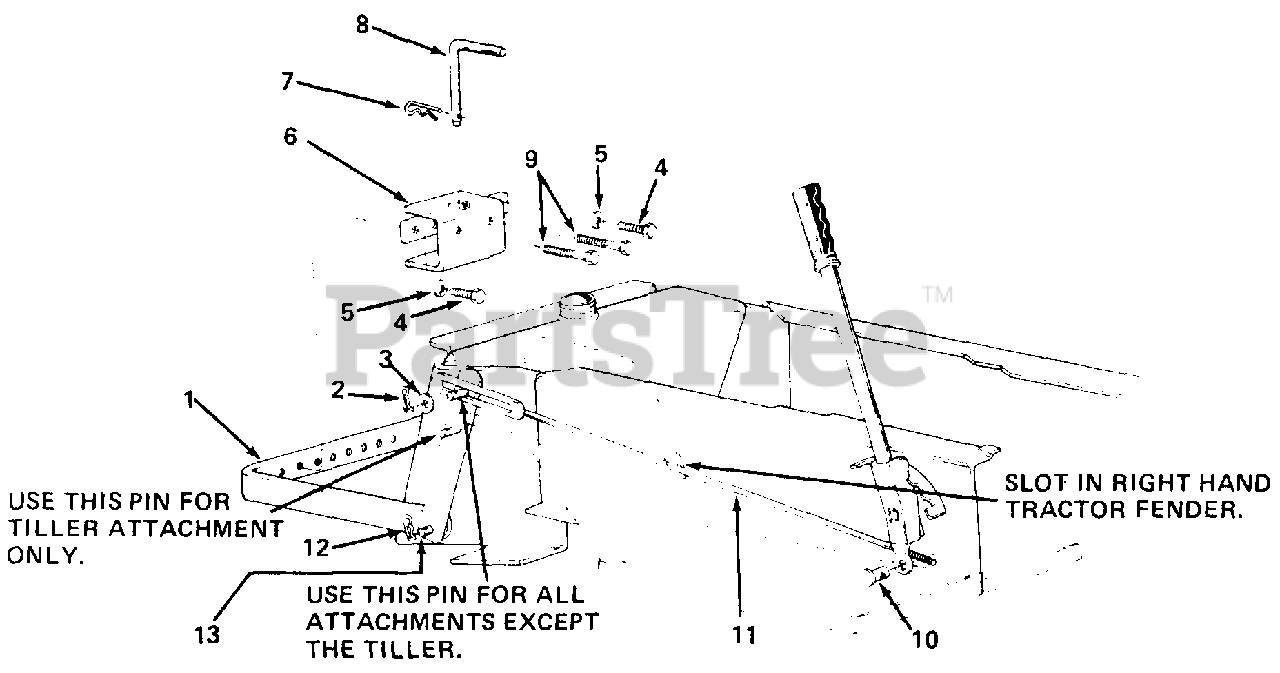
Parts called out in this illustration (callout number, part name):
3	Fl.-Wash. 1/2" I.D.
4	Hex Scr. 1/2-13 x 1.00 Lg.
5	L-Wash. 1/2 Scr.
8	Hitch Pin
9	Hex Scr. 1/2-13 x 3.00' Lg.
10	Adjustment Ferrulle
13	Hitch Rod
